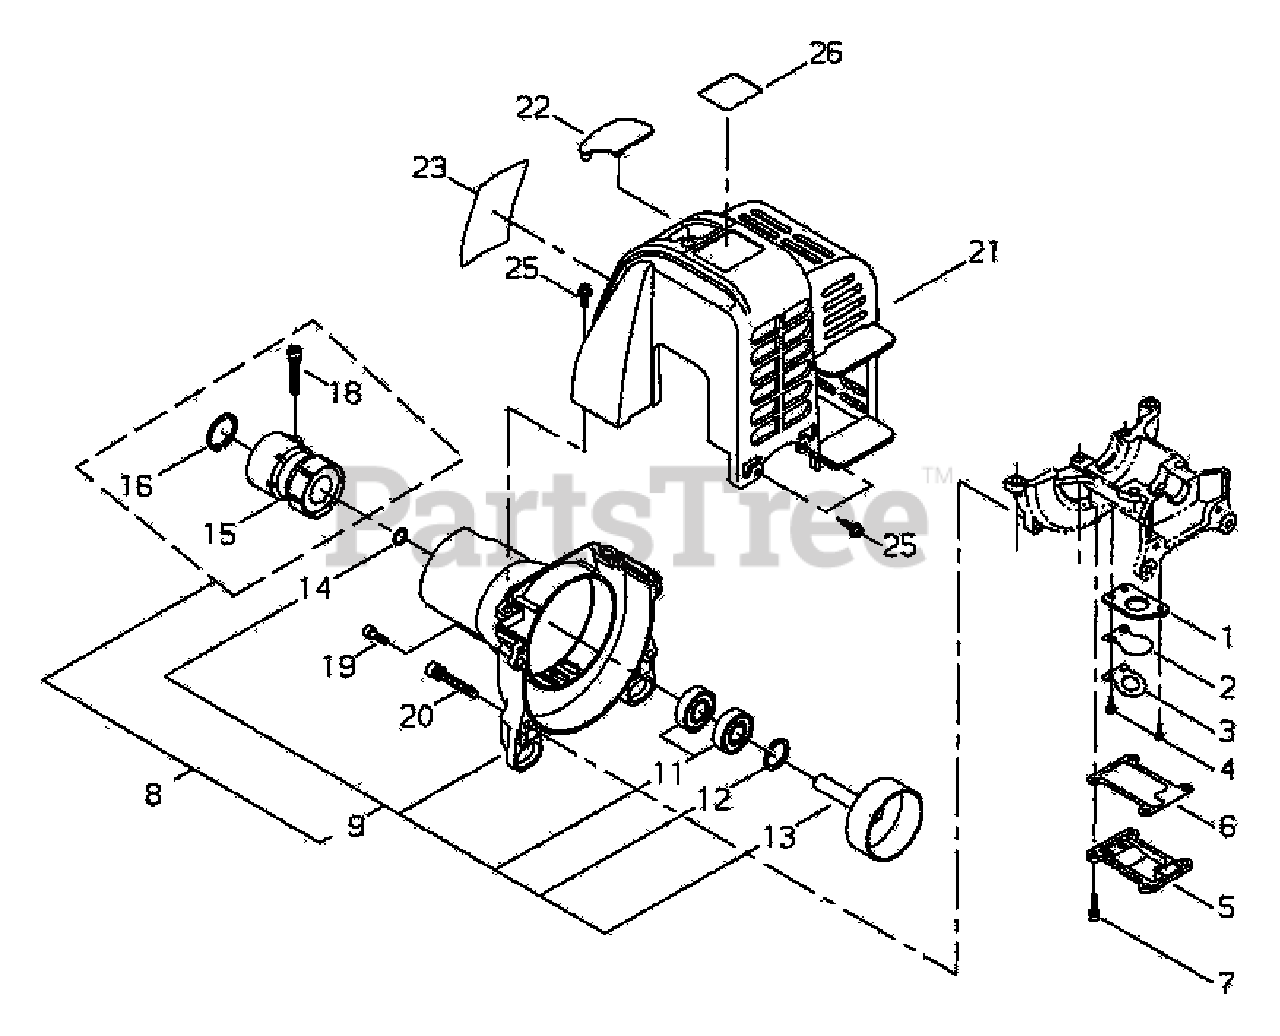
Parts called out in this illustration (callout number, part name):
1	PLATE, REED BACKING
2	VALVE, REED
3	STOP, REED VALVE
4	SCREW M3×10
5	COVER, REED VALVE
6	GASKET, REED VALVE
7	BOLT M4×12
8	FAN CASE ASSY
9	FAN CASE ASSY
11	BEARING, BALL 6000ZZ
12	RING, SNAP Ø26
13	DRUM, CLUTCH
14	RING, SNAP WR10
15	CUSHION, AV
16	RING, SNAP Ø40
18	BOLT M5×22
19	BOLT 5×16
20	BOLT M5×45
21	COVER, ENGINE
22	COVER, SPARK PLUG
23	LABEL, C4 SHINDAIWA
25	BOLT M4×16
26	LABEL - MODEL
